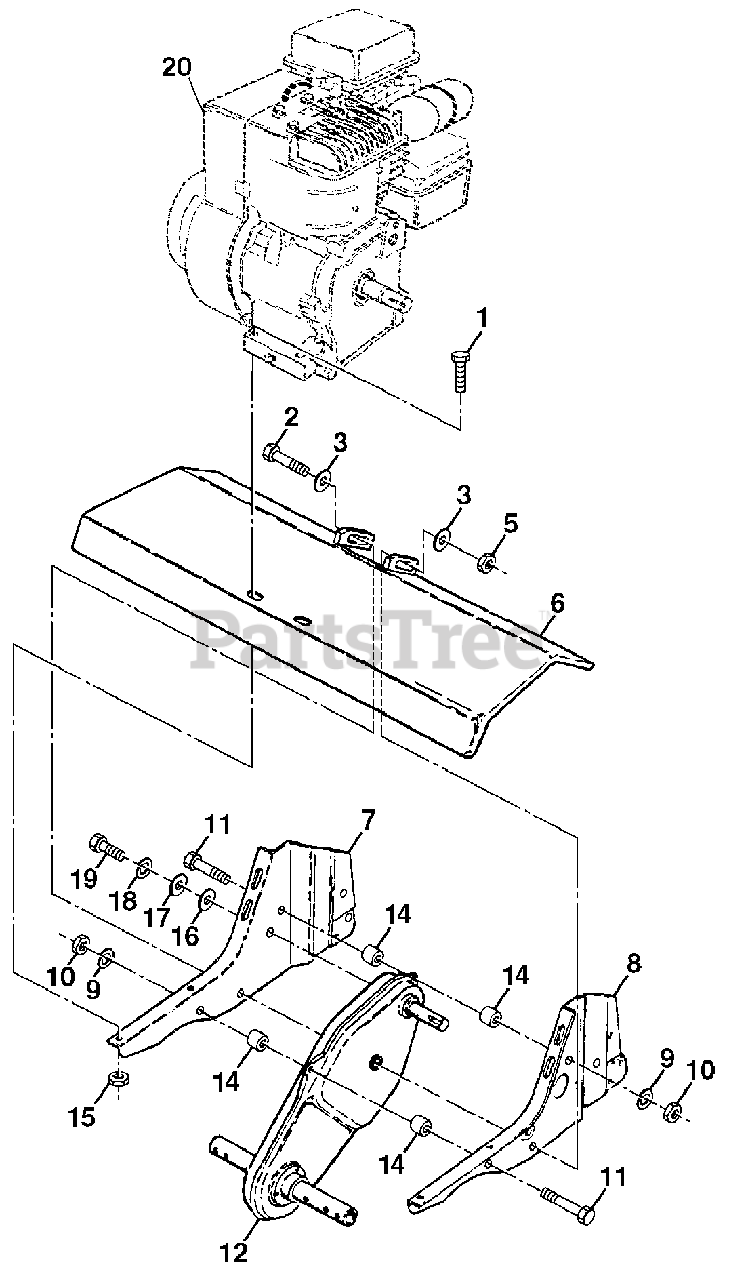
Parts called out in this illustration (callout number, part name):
1	Bolt, Hex 5/16-18 x 1-1/2 Gr. 2
2	Bolt, Hex, Fin 3/8-16 x 3-1/4
3	Washer 13/32 x 13/16 x 11
5	Locknut, Hex, w/washer 3/8-16
6	Shield, Tine
7	Bracket, Engine, R.H.
8	Bracket, Engine, L.H.
9	Washer, Lock 5/16
10	Nut, Hex 5/16-18
11	Bolt, Hex 5/16-18 x 2-3/4
12	Transmission
14	Spacer, Split
15	Nut, Keps 5/16
16	Washer 9/32 x 7/8 x 12 Ga.
17	Washer 9/32 x 1-1/4 x 16 Ga.
18	Washer, Lock 1/4
19	Bolt, Hex 1/4-28 x 3/4 Gr. 5
